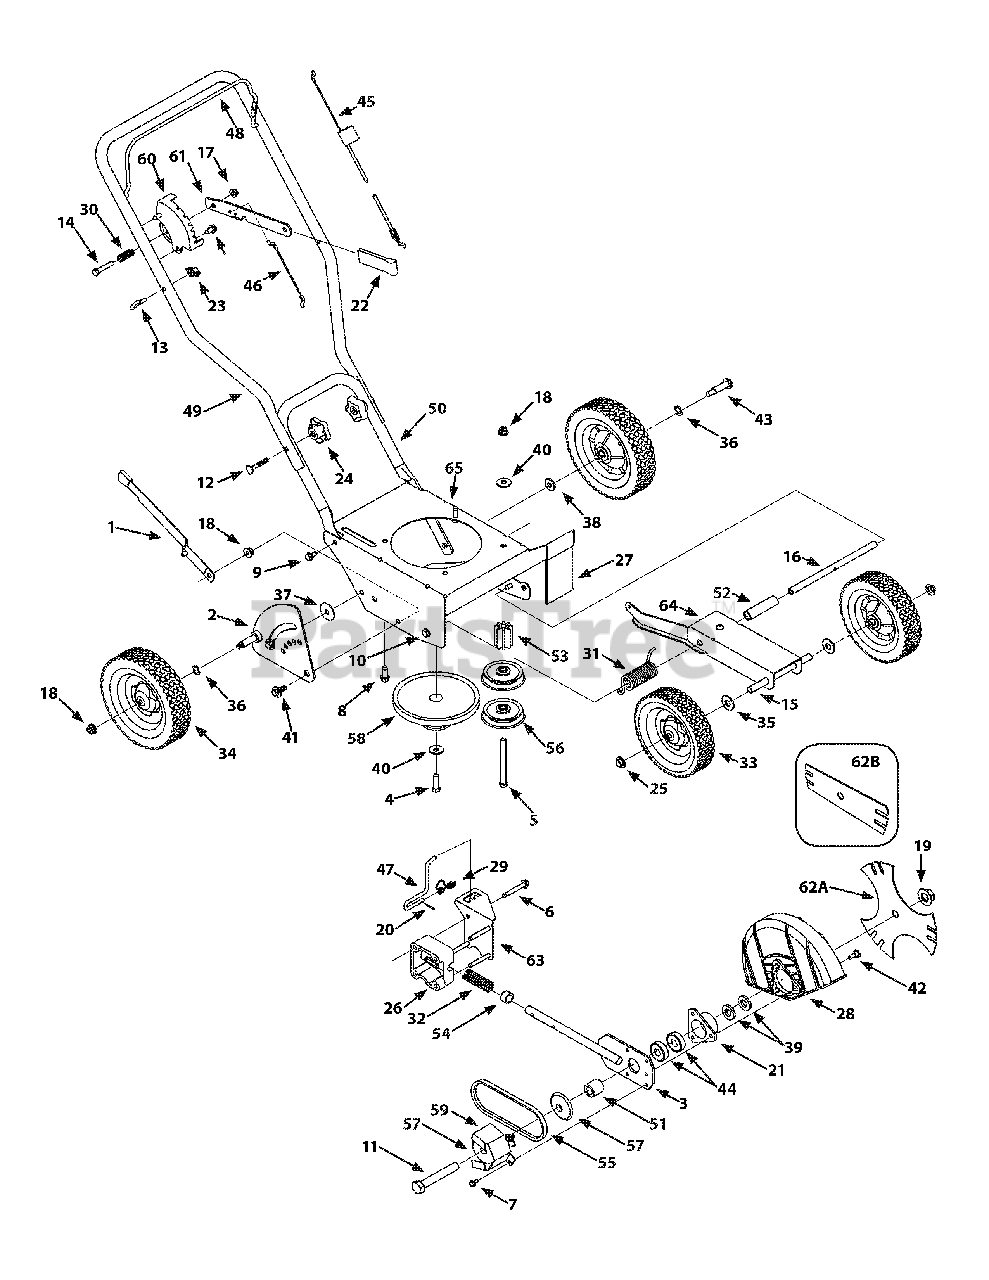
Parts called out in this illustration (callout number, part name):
1	Curb Height Adjustment Lever
2	Curb Height Adjuster Plate
3	Blade Plate Assembly
4	Screw 3/8-24 x 1.25
5	Screw 3/8-16 x 4.00
6	Hex Screw, 5/16-18
7	Self-tapping Screw, 1/4-20
8	Screw, 3/8-16
9	Hex Screw, 5/16-12
10	Hex Screw 3/8-16 x .625
11	Hex Screw, 5/8-18 x 4.0
12	Carriage Bolt, 5/16-18 x 2.0
13	Rope Guide (Eye Bolt)
14	Hex Screw, 5/16-18
15	Axle Shaft .50x6.65
16	Frame Spacer .50x9.25
17	Lock Flange Nut, 5/16-18
18	Flange Nut 3/8-16
19	Flange Nut, 5/8-18
20	Clevis Pin 3/32 x .625
21	Bearing Cup
25	Push Cap 1/2" rod
26	Bearing Block
27	Debris Guard
28	Blade Guard
29	Double Torsion Spring
30	Compression Spring
31	Torsion Spring
32	Compression Spring
33	Wheel 7 x 1.75 T-Tread
34	Wheel 8 x 1.75 T-Tread
35	Flat Washer 1/2 x 1.25 x .10
36	Wave Washer .531 x .781 x .013
37	Flat Washer, .385 x 1.5 x .075
38	Flat Washer .385 x 1.0 x .135
39	Flat Washer .635x1.24x.181
40	Bell Washer,.396 x 1.140
41	Shoulder Screw, 3/8-16
42	Shoulder Screw, 3.75 x .280 x 1/4-14
43	Shoulder Screw, 3/8-16
44	Bearing, .625 ID x 1.57 OD
45	Control Cable (Briggs & Stratton)
46	Wheel Adjustment Cable
47	Blade Adjustment Rod
48	Bail Handle
49	Upper Handle
50	Lower Handle
51	Spacer, .63 x 1.12 x 1.06
53	Pulley Mount Spacer
54	Spacer, .64 x.88 x .50
56	Flat Idler Pulley, 2.5 OD
58	Combination Flywheel Pulley
61	Depth Index Lever
62A	Tri-Star Blade
63	Bracket Plate
64	Dual Wheel Bracket
65	Frame
